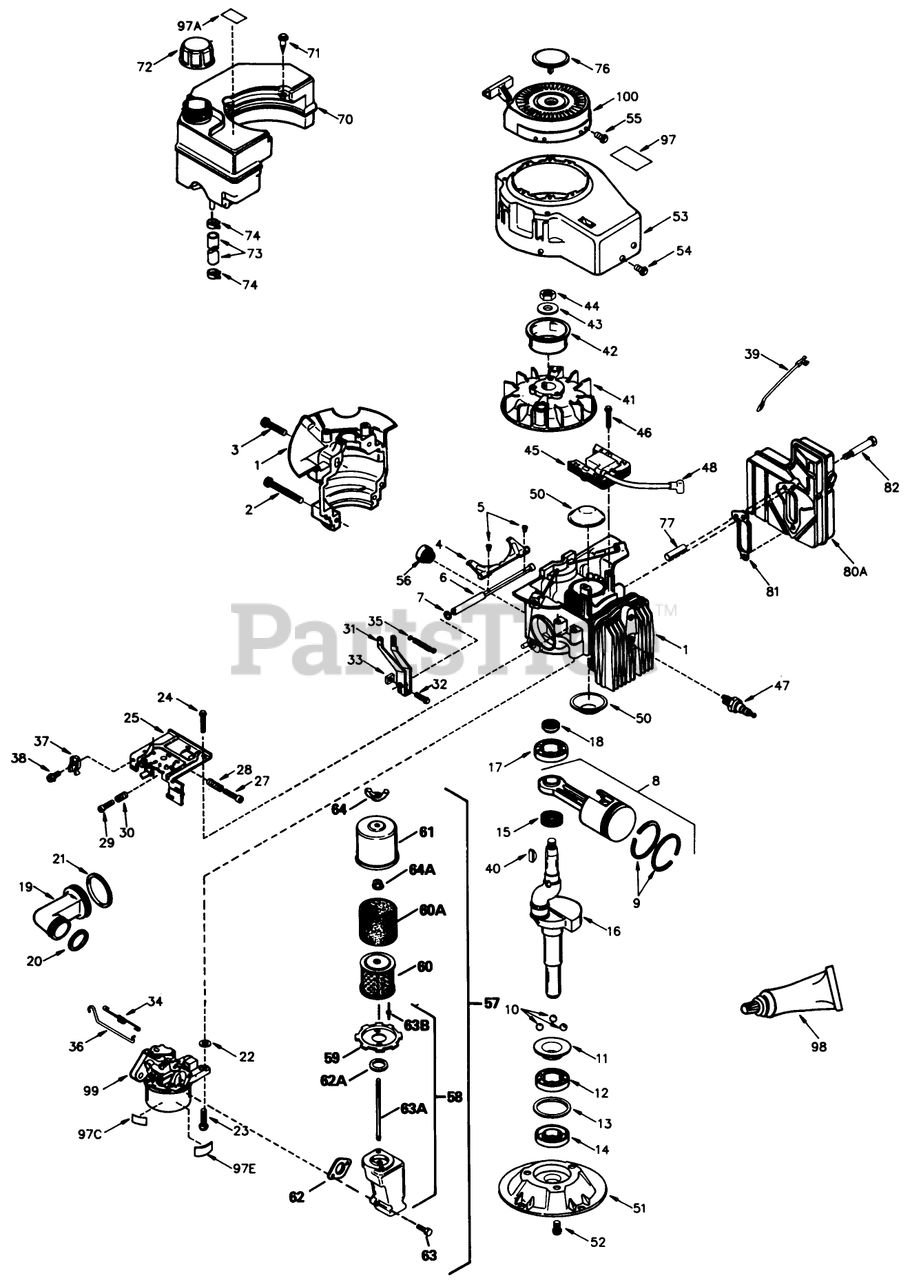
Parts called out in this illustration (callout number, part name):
2	Screw
3	Screw
4	Governor Lever
5	Screw-Shutter
6	Governor Shaft
7	Oil Seal
8	Piston Rod Assy. (Incl. Ref. #9 15)
9	Ring Set-Piston
11	Ring-Slide
12	Ball Bearing
13	Bearing Retainer
14	Oil Seal
15	Bearing-Strip
16	Crankshaft
17	Ball Bearing
18	Oil Seal
19	Intake Pipe Assy. (Incl. Ref. #20 21
20	O Ring
21	O Ring
22	Washer-Bowl Nut
23	Screw-Hex. Washer Hd.
24	Screw (10-24 x 3/8)
25	Control Bracket Assy. (Incl. Ref. #27 thru 30)
27	Screw-Phillips Hd.
28	Spring
29	Screw
30	Spring-Compression
31	Lever-Governor
32	Screw
33	Nut-Lock
34	Spring-Throttle Link
35	Spring-Governor
36	Link-Governor
37	Conduit
38	Screw-Hex. Hd.
39	Wire-Ground
40	Key-Flywheel
41	Flywheel
42	Cup-Starter
43	Washer-Belleville
44	Nut-Flywheel
45	Solid State
46	Screw
47	Spark Plug-Resistor (R C J 8Y)
48	Cover-Spark Plug
50	Cover-Port
51	Adapter
52	Screw-Hex. Washer Hd.
53	Housing-Blower
54	Screw
55	Screw, Hex Hd.
56	Filter-Fuel
57	Dual Upright Canister Air Cleaner Kit (Incl. Ref. #58, 60, 60A, 61, 62, 63, 64 97B)
58	Elbow Assy., Air Cleaner (Incl. Ref. #59, 62A, 63A 63B)
59	Bracket-Air Cleaner
60	Filter, Air Cleaner (incl. Ref. #64A)
60A	Filter-Pre-Air
61	Body, Air Cleaner
62	Gasket-Air Cleaner
62A	Gasket, Air Cleaner
63	Screw, Fil hd.
63B	Rivet-Pop
64	Nut-Wing
64A	Nut Lockwasher
70	Fuel Tank Assy.
71	Screw-Hex. Hd.
72	Cap-Fuel
73	Line-Fuel (8.62)
74	Clamp-Line, Fuel
76	Plug Starter
80A	Muffler
81	Gasket-Muffler
82	Screw-Hex. Hd.
97	Decal-Name
97A	Decal-Fuel Mixture
97C	Decal-Primer
97E	Decal-Instruction
98	Gasket Eliminator
99	Carburetor (Incl. Ref. #20)
100	Starter-Rewind
